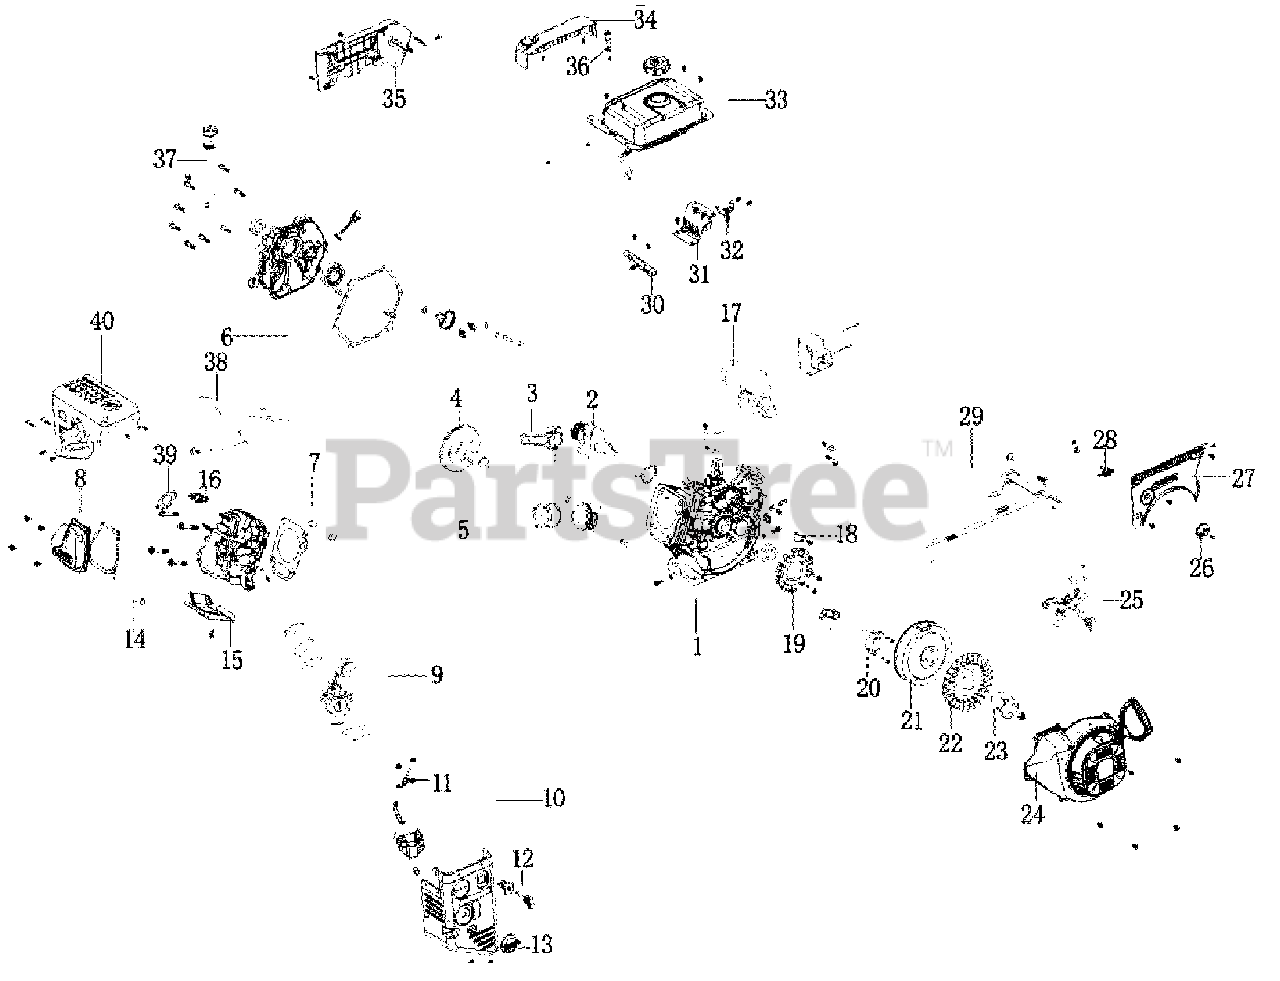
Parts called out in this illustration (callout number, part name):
1	CRANK CASE
2	CRANKSHAFT COMP
3	ROD ASSY ., CONNECTING
4	CAMSHAFT ASSY
5	PISTON
6	CRANK CASE COVER
7	HEAD COMP .,CYLINDER
8	COVER COMP ., HEAD
9	CARBURETOR
10	AIR CLEANER
11	CHIOKE SET
12	KEY SWITCH
13	CHOKE LEVER
14	TUBE , BREATHER
16	PLUG , SPARK
17	STARTER,MOTOR
18	PLATE,WINDING
19	COIL ASSY .
20	COIL ASSY . , IGNITION
21	FLYWHEEL COMP
22	FAN COOLING
23	PULLEY,STARTER
24	STARTER ASSY.
25	CONTROL ASSY.
26	KNOB FUEL SWITCH
27	COVER, ENGINE
28	FUEL SWITCH
29	ARM, GOVERNOR
30	HOLDER,FUEL TANK
31	HOLDER,FUEL TANK
32	HOLDER,ELECTRIC STARTING BOX
33	TANK COMP ., FUEL
34	REAR SOVER TANK
35	COVER, ENGINE
36	A HANGER
37	CAP ASSY.
38	SHROUD
39	GASKET , EX.PIPE
40	MUFFLER
